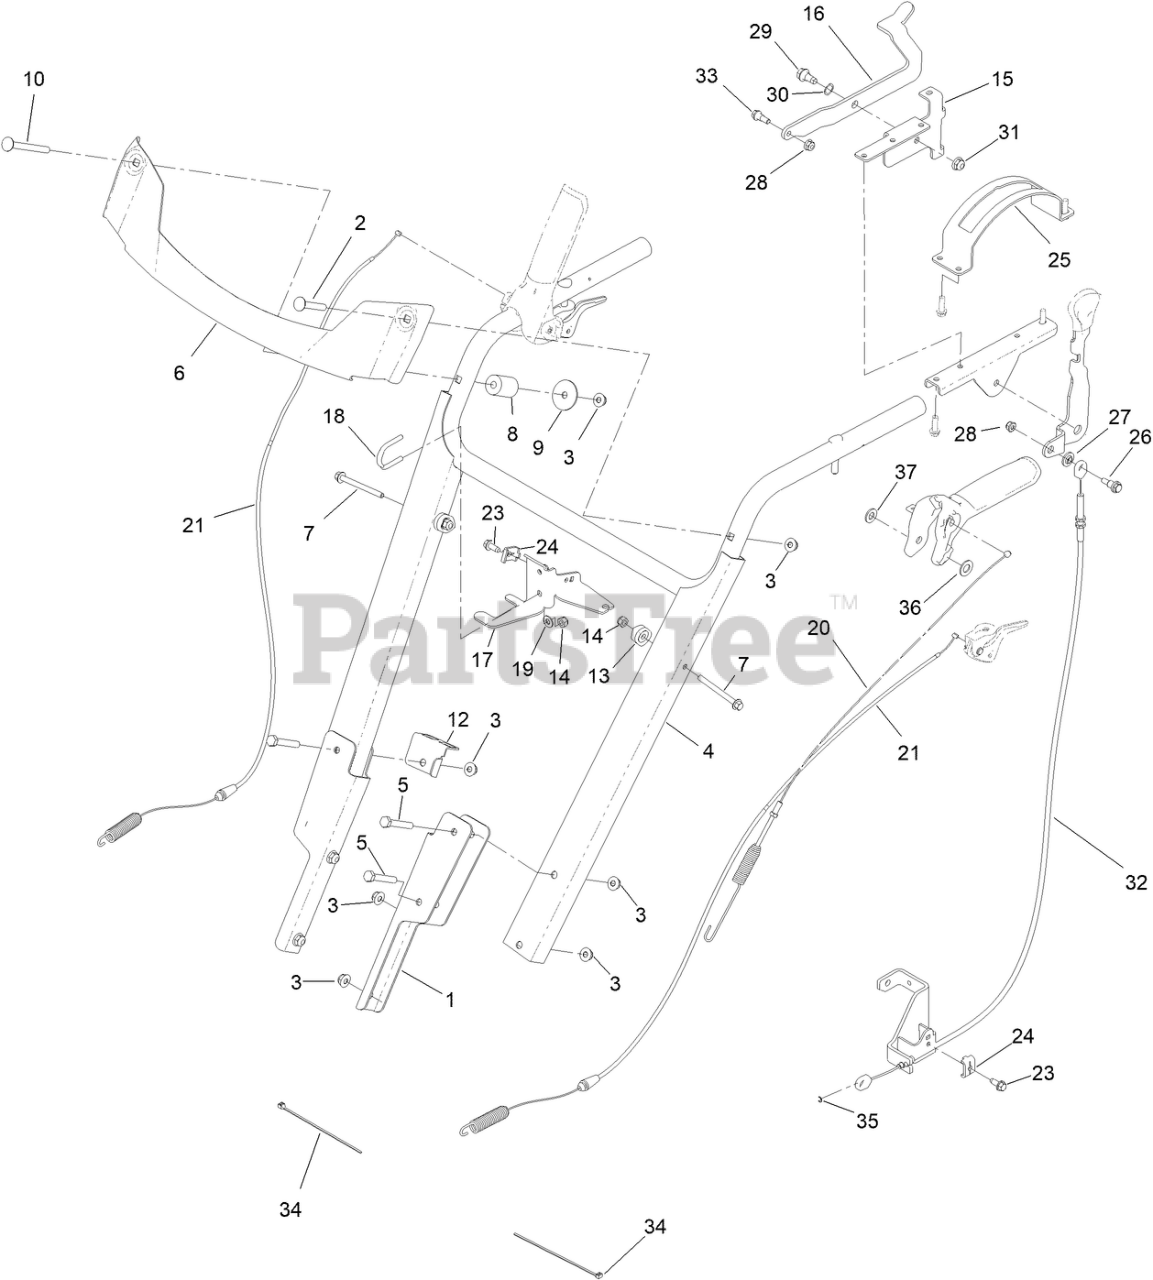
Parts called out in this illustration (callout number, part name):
1	BRACKET-HANDLE, LOWER
2	SCREW-CARR
3	NUT-HF
4	HD HANDLE ASM
5	SCREW-HH
6	TRIM-METAL, HD
7	SCREW-HHF
8	SPACER
9	WASHER-FLAT
10	SCREW-CARR
12	BRACKET-STICK, CLEANOUT
13	CLAMP-CABLE
14	NUT-HEX
15	BRACKET-LEVER
16	LEVER-ADJUSTMENT, TRACK
17	BRACKET-CABLE, SPEED
18	CLAMP-LIGHT
19	WASHER-FLAT
20	CABLE-TRACTION
21	CABLE-CLUTCH
23	SCREW-HWH
24	CLAMP-CABLE
25	GATE-SHIFT, SPEED
26	BOLT-SHOULDER
27	WASHER-STEPPED
28	NUT-FLANGE, NI
29	SCREW-SHOULDER
30	WASHER, WAVE
31	NUT-HF
32	CABLE-HYDRO, PUSH PULL
33	BOLT-SHOULDER
34	TIE-CABLE
35	RING-RETAINING, EXT
36	WASHER-FLAT
37	WASHER-FLAT
